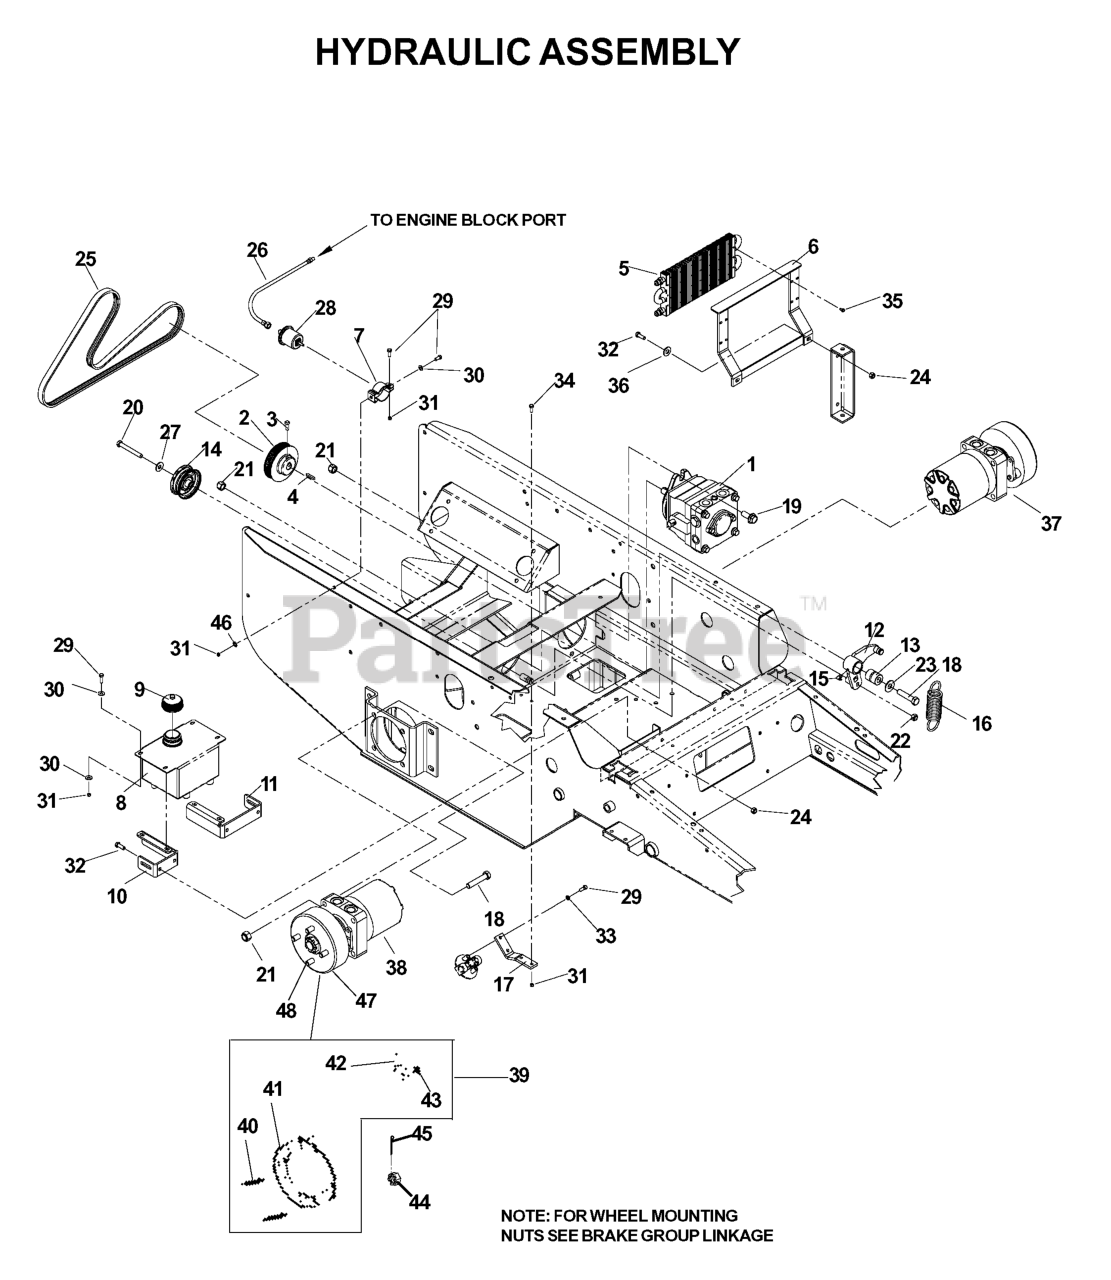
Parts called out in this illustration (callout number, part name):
1	HG_PUMP CCW RH
2	PUMP SHEAVE
3	SCREW 5/16C X 1 SQ HEAD SET
4	KEY, METRIC
6	COOLER WLDMT MT
7	CLAMP-OIL SENDER
8	TANK, OIL = PAINTED
9	HYDRAULIC CAP
10	TANK MOUNT RT
11	TANK MOUNT LT
12	ARM WELDMENT
14	IDLER PULLEY
17	FILTER MOUNT - PAINTED
18	HEX SCREW 1/2-13 X 2.5" GR 5
19	HCS 1/2C X 1 1/4 SERRATED HEAD
20	HCS 3/8C X 3
21	NUT 1/2-13 HEX NYLOC ZD
22	NUT 3/8-16 NYLOC
23	WASHER 1/2 FLAT
24	NUT 5/16 NYLOC
27	WASHER 3/8 SAE FLAT
28	SENDER,OIL PRESS
29	HCS 1/4C X 3/4 HCS
30	WASHER 1/4 FLAT
31	NUT.1/4-20.HEX.NYLOC.ZD
32	HCS 5/16C X 1
33	LOCKWASHER 1/4"
34	HCS 1/4 X 1
35	SCR #10-12X3/4 HEX WAS HD ZD
36	WASHER 5/16 FLAT
37	WHEEL MTR ASM
38	WHEEL MTR ASM, RT
39	SHOE ASM.
40	RETURN SPRING
44	CASTLE-NUT
45	COTTER PIN
46	WASHER 1/4 EXTLW STAR ZD
48	WHEEL STUD 1/2-20X1-3/8 GR8 ZN
